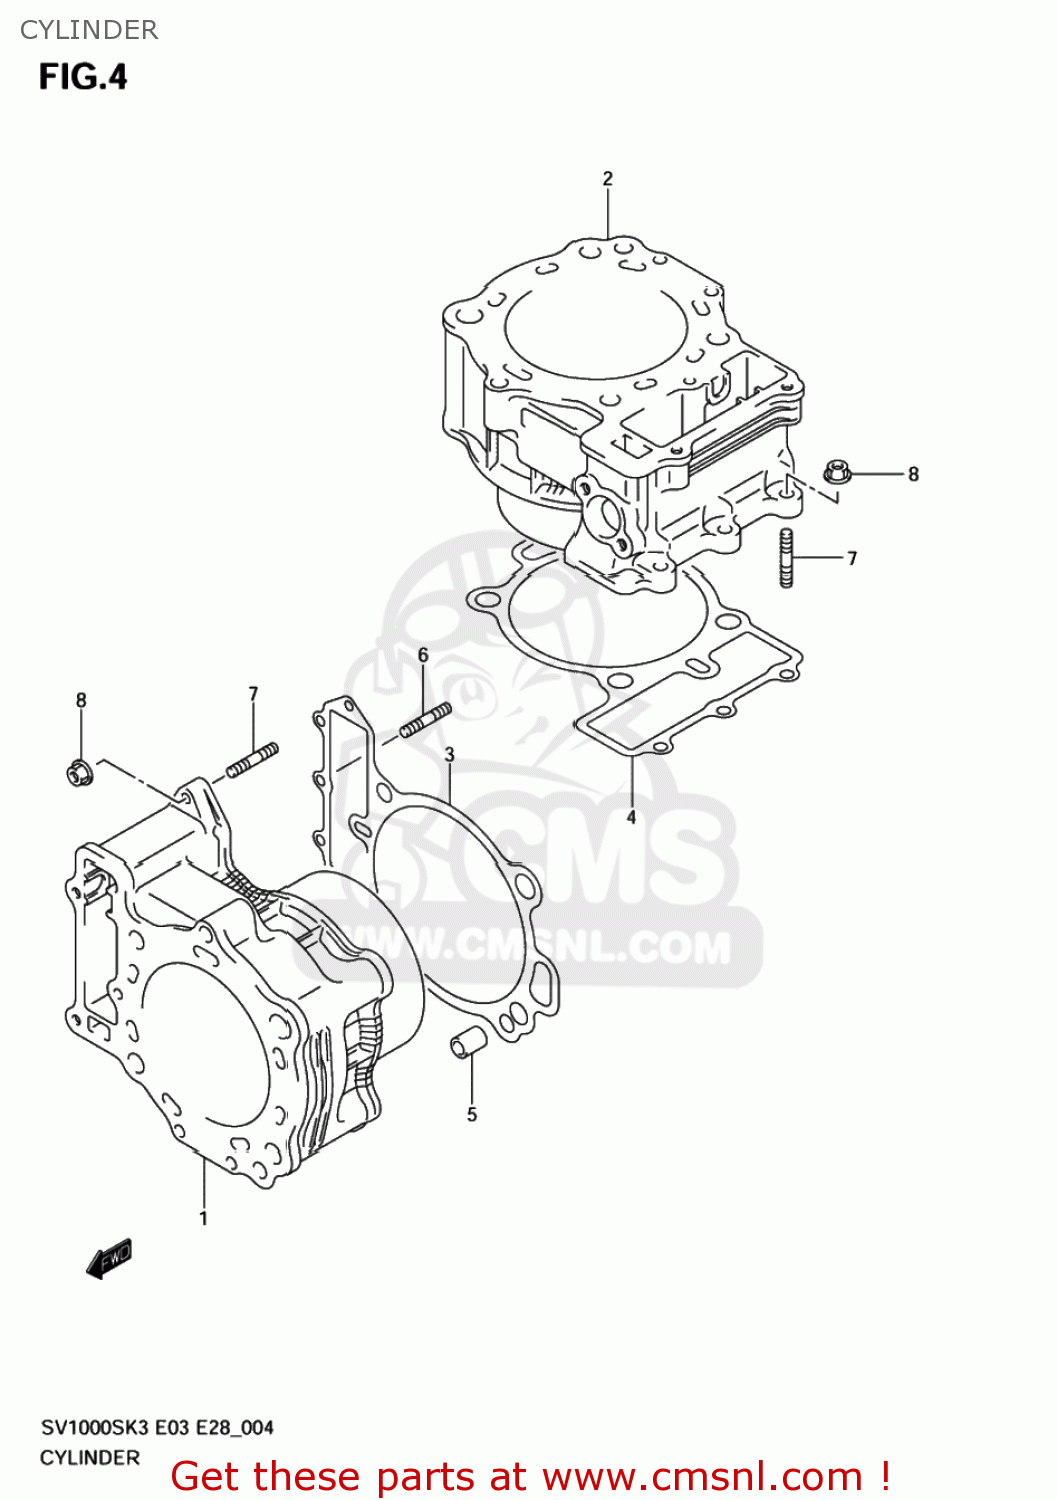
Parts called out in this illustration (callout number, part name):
1	CYLINDER,FR
2	CYLINDER,RR
3	GASKET,CYLINDER FR (NAS)
4	GASKET,CYLINDER RR (NAS)
5	PIN
6	STUD BOLT (L:20)
7	STUD,M6X1X32
8	NUT
